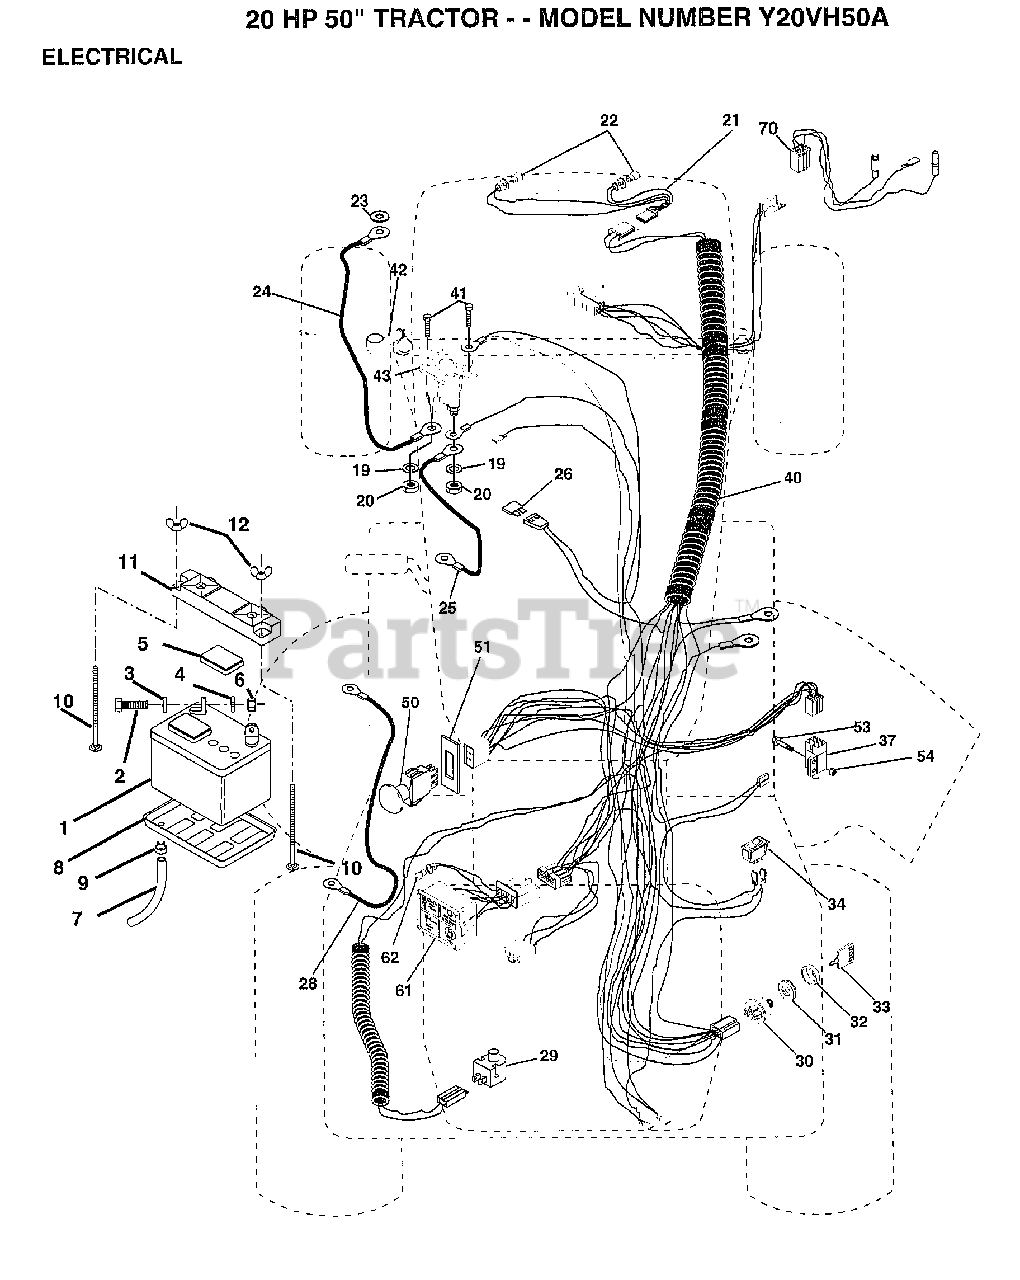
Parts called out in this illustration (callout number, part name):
2	BOLT LT
3	LOCKWASHER
4	WASHER
5	"CAP,BATTERY "
7	"DRAIN TU T, BATT"
8	"TRAY T, BATTERY"
9	HOSE CLAMP T
10	BOLT
20	NUT
22	HEADLAMP BULB
23	LOCKWASHER
24	"CABLE T, BATTERY"
25	CABLE-BATTERY T
26	FUSE HYT
28	CABLE T
29	SWITCH SEAT
32	COVER KEY SWITCH
33	KEY MLD GEN DELTA
34	SWITCH LT
37	SWITCH INTERLOCKT
40	HARNESS IGNITION
41	SCREW
51	RING RETAIN PTO
53	SCREW
54	"NUT,KEPS"
61	LIGHT.PKG.ASM.
62	BULB LIGHT T
70	HARNESS.ENG.VANII
